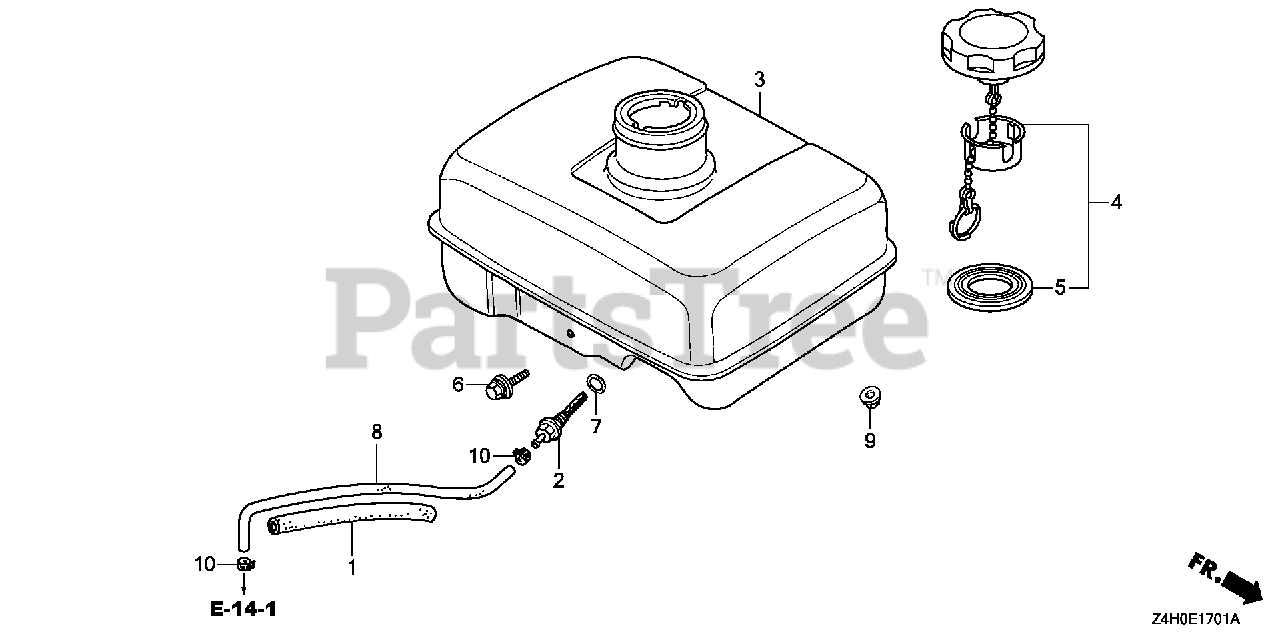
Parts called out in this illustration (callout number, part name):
1	RUBBER, SUPPORTER (107MM)
2	JOINT, FUEL TANK
3	TANK, FUEL *NH105* (MAT BLACK)
3	TANK, FUEL *T51* (JACOBSEN ORANGE)
4	CAP, FUEL FILLER
5	GASKET, FUEL FILLER CAP (39X62X3) (RADICON)
6	BOLT, FLANGE (6X29)
7	O-RING (13.5X1.5) (ARAI)
7	O-RING (14MM) (NOK)
8	TUBE, FUEL (4.5X140) (FKM)
9	NUT, FLANGE (6MM)
10	CLAMP, TUBE (D8)
